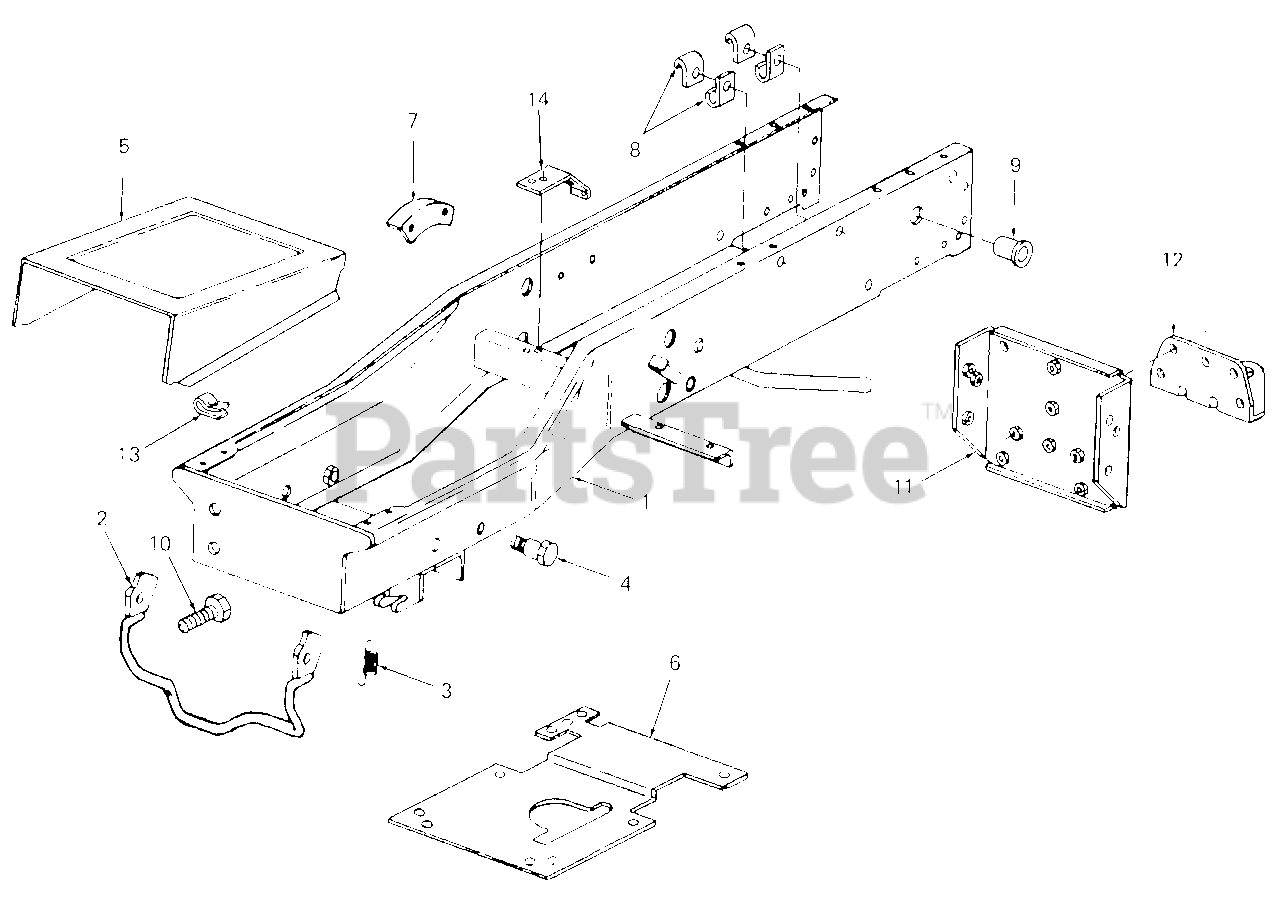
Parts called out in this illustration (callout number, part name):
3	Spring, Latch
4	Bolt, Shoulder
5	Cover, Frame w/Graphic
7	Bracket, Height Indicator
8	Clip, Cable
9	Bushing, Snap
10	Screw, Adjustment, 1/2-20 X 1.0 Lg GR5
13	Nut, Speed
14	Bracket, Switch
